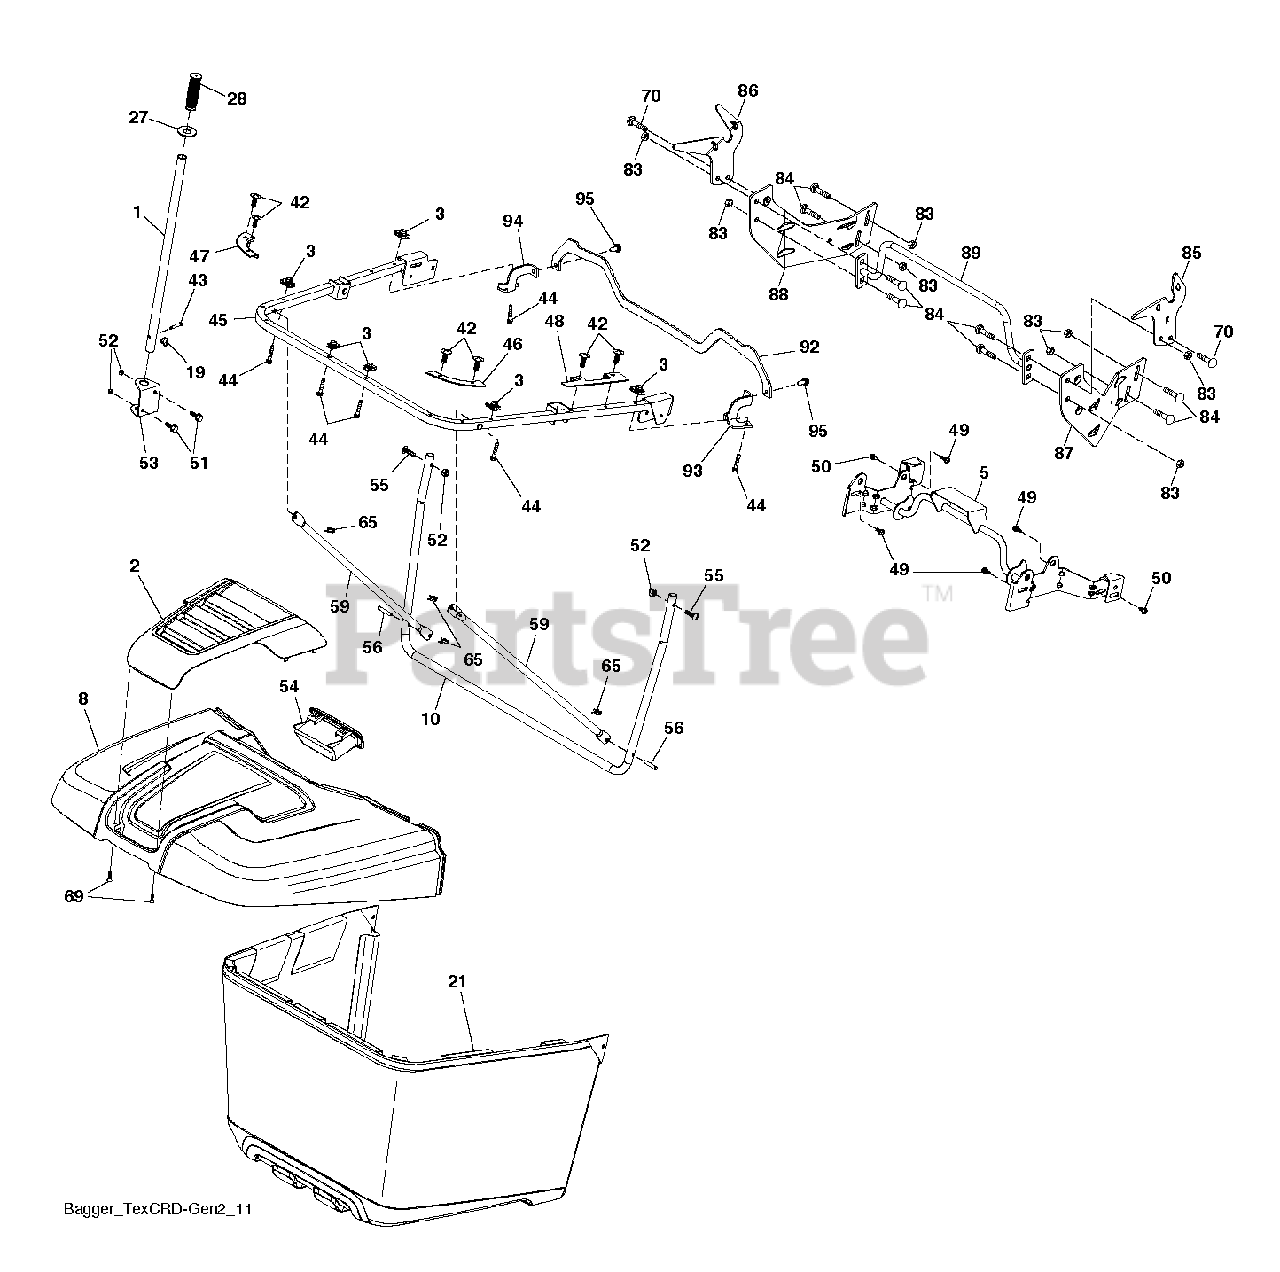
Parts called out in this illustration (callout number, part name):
1	TUBE.HANDLE.BAGGER.CRD/SRD.BLA
2	APPLIQUE.BAGGER
3	1/4-20 U NUT
5	FRAME TEX_CRD_GEN2 UPPER PIVOT
8	BAGGER TOP
10	FRAME TEX_CRD_GEN2 BAGGER FRAM
19	PIN.COTTER.5/16.BOW TI
21	BAGGER.ASM.FABRIC.CRD.GII.HUSQ
27	GROMMET RUBBER GROMMET, DUMP T
28	GRIP.HANDLE.BLACK
42	CLIP CHRISTMAS TREE CLIP
43	RIVET,DRILLED
45	FRAME TEX_CRD_GEN2 UPPER U FRA
46	CONNECTOR RIGHT BAGGER CORNER
47	CONNECTOR LEFT BAGGER CORNER C
48	BAFFLE BAGGER SIDE CLOSE-OUT
49	BOLT, SHOULDER 5/16-18
50	BOLT, 5/16-18 X 1 3/4
51	BOLT.CARR.SQNK.5/16-18UNC.X3/4
52	NUT.71038.31-18.HEX.NYLOCK
53	BRACKET DUMP HANDLE BRACKET, T
54	HANDLE BAGGER TOP FRONT HANDLE
55	BOLT
56	PIN.CLEVIS.183
59	TUBE BAGGER SPREADER TUBE, TEX
65	RETAINER M
69	SCREW,#8.FLAT.HEAD.DRILL.TIP
70	SCREW, 3/8-16X3/4
83	NUT
84	BOLT D
85	BRACKET.RH.PIVOT.MAN.DUMP.BLAC
86	BRACKET.LH.PIVOT.MAN.DUMP.BLAC
87	BRACKET.RH.MID.SUP.BAG.TEX.CRD
88	BRACKET.LH.MID.SUP.BAG.TEX.CRD
89	TUBE.WELD.OFSET.STRUT.BAG.X431
92	BRACKET.PNT.BAGGER.TOP.SUPPORT
93	BRACKET.PNT.RH.SUPPORT.ATTACH
94	BRACKET.PNT.LH.SUPPORT.ATTACH
95	SCREW
